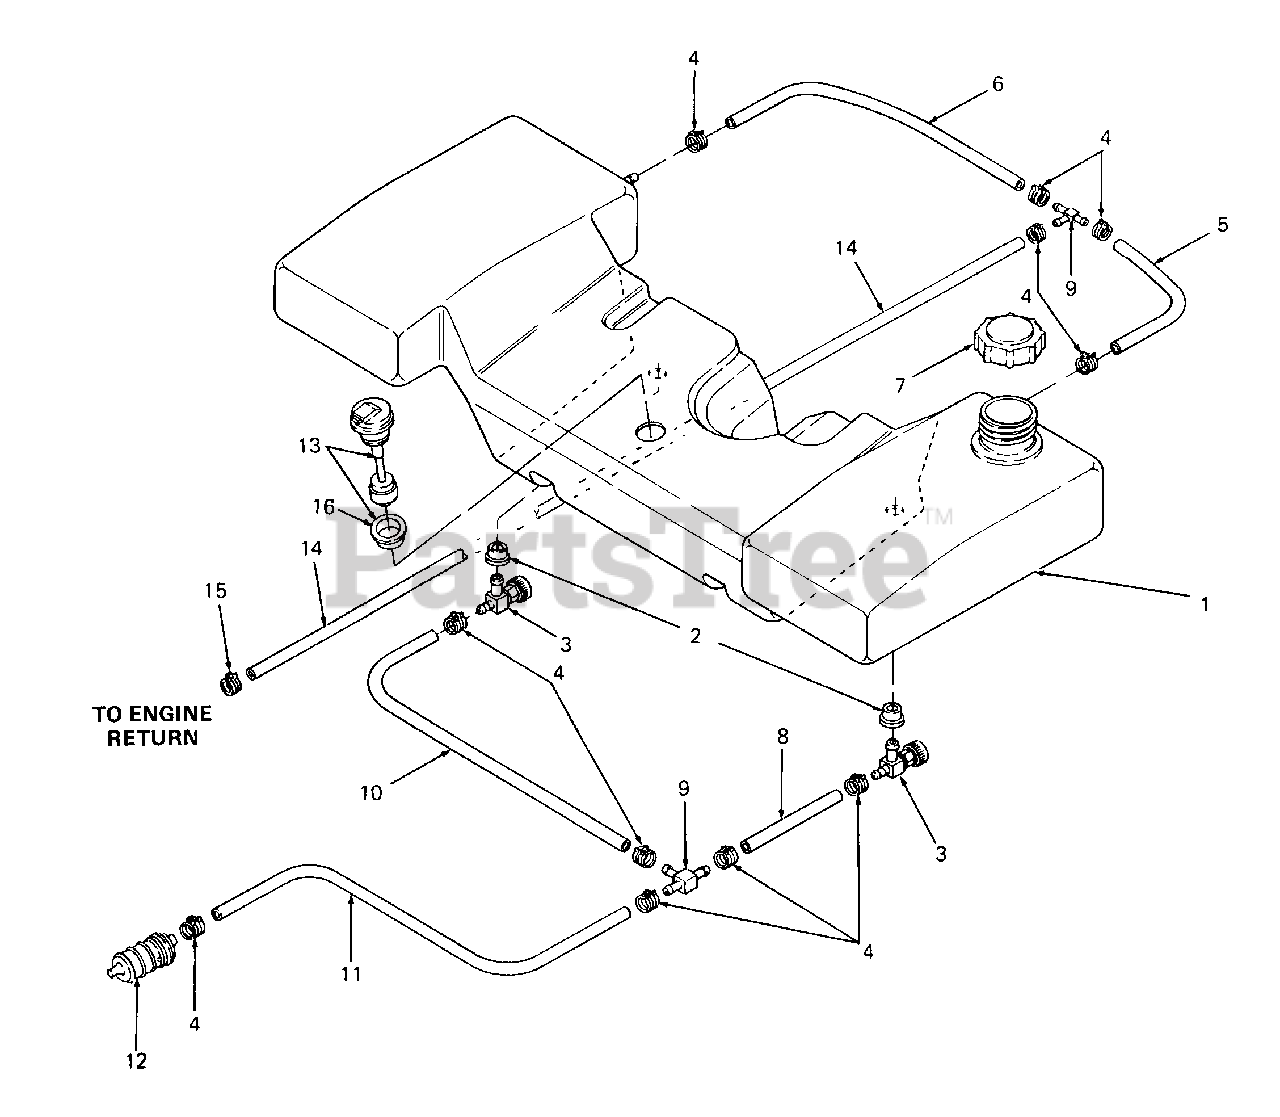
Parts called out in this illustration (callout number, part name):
1	Tank Fuel
2	Bushing
3	Valve, Fuel Shutoff
4	Clamp, Hose
5	Line, Fuel -9" Lg
6	Line, Fuel -14" Lg
7	Cap, Fuel
8	Line, Fuel -5" Lg
9	T-Fitting
10	Line, Fuel -19" Lg
11	Line, Fuel -38" Lg
12	Filter, Fuel
13	Sensor, Low Fuel
14	Line, Fuel -73" Lg
15	Clamp, Hose
16	Bushing, Rubber
